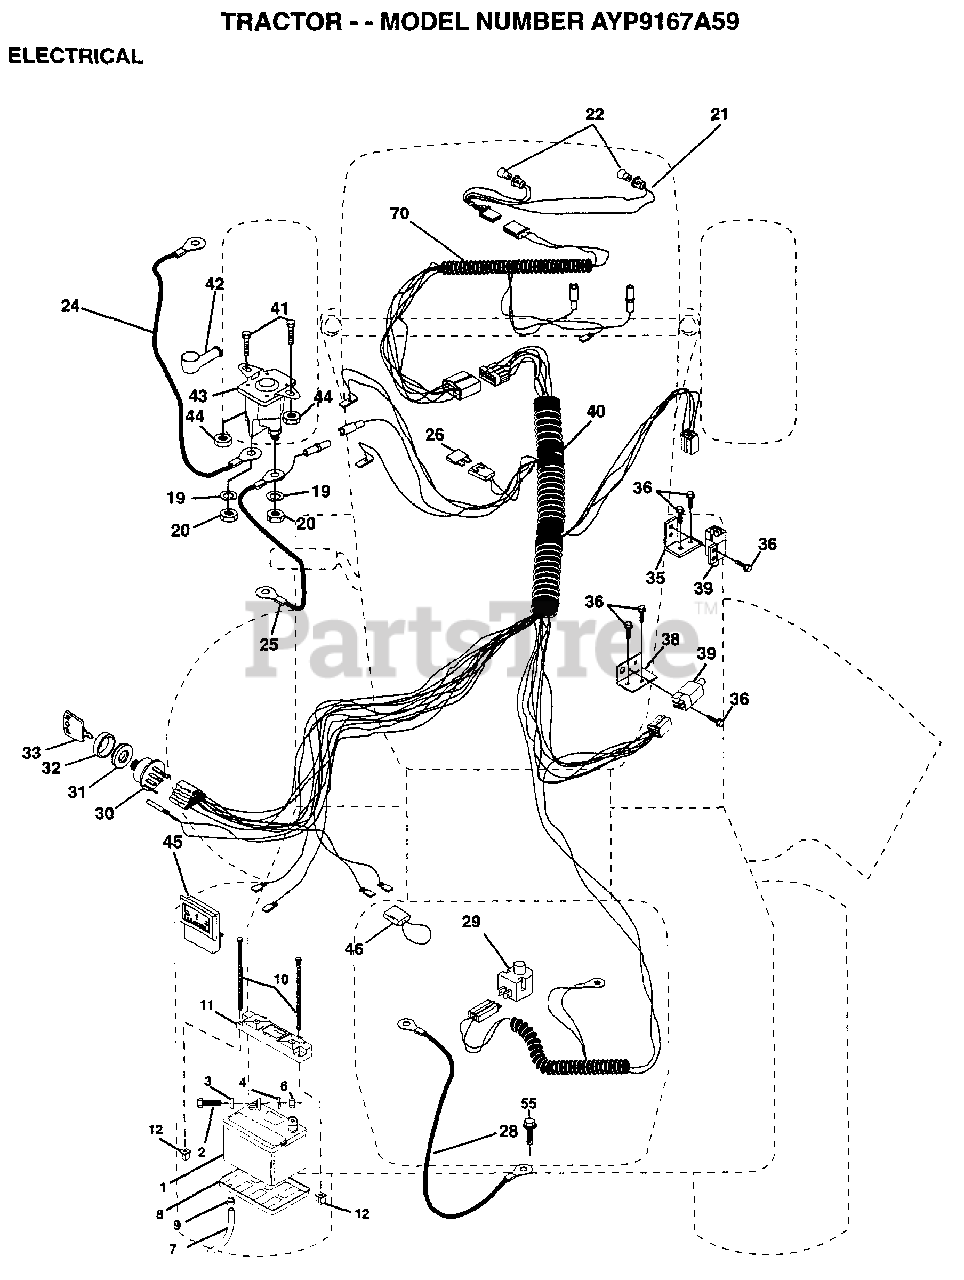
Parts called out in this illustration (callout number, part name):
2	BOLT LT
3	WASHER
4	LOCKWASHER
7	"DRAIN TU T, BATT"
8	"TRAY T, BATTERY"
9	HOSE CLAMP T
20	NUT
21	"HARNESS,LIGHT SOC"
22	HEADLAMP BULB
24	"CABLE T, BATTERY"
25	CABLE.6GA.22W/16W
26	FUSE HYT
28	CABLE.GRND.6GA.21
29	SWITCH SEAT
30	SWITCH IGN 4POS
31	NUT IGNITION
32	COVER KEY SWITCH
33	KEY
35	BRACKET LT
36	SCREW
38	BRACKET SWITCH IN
39	SWITCH INTERLOCKT
41	BOLT.HX.1/4-20
44	NUT
45	AMMETER
46	PROTECTION LOOP
55	SCREW LT
70	HARNESS.ENG.LT.
